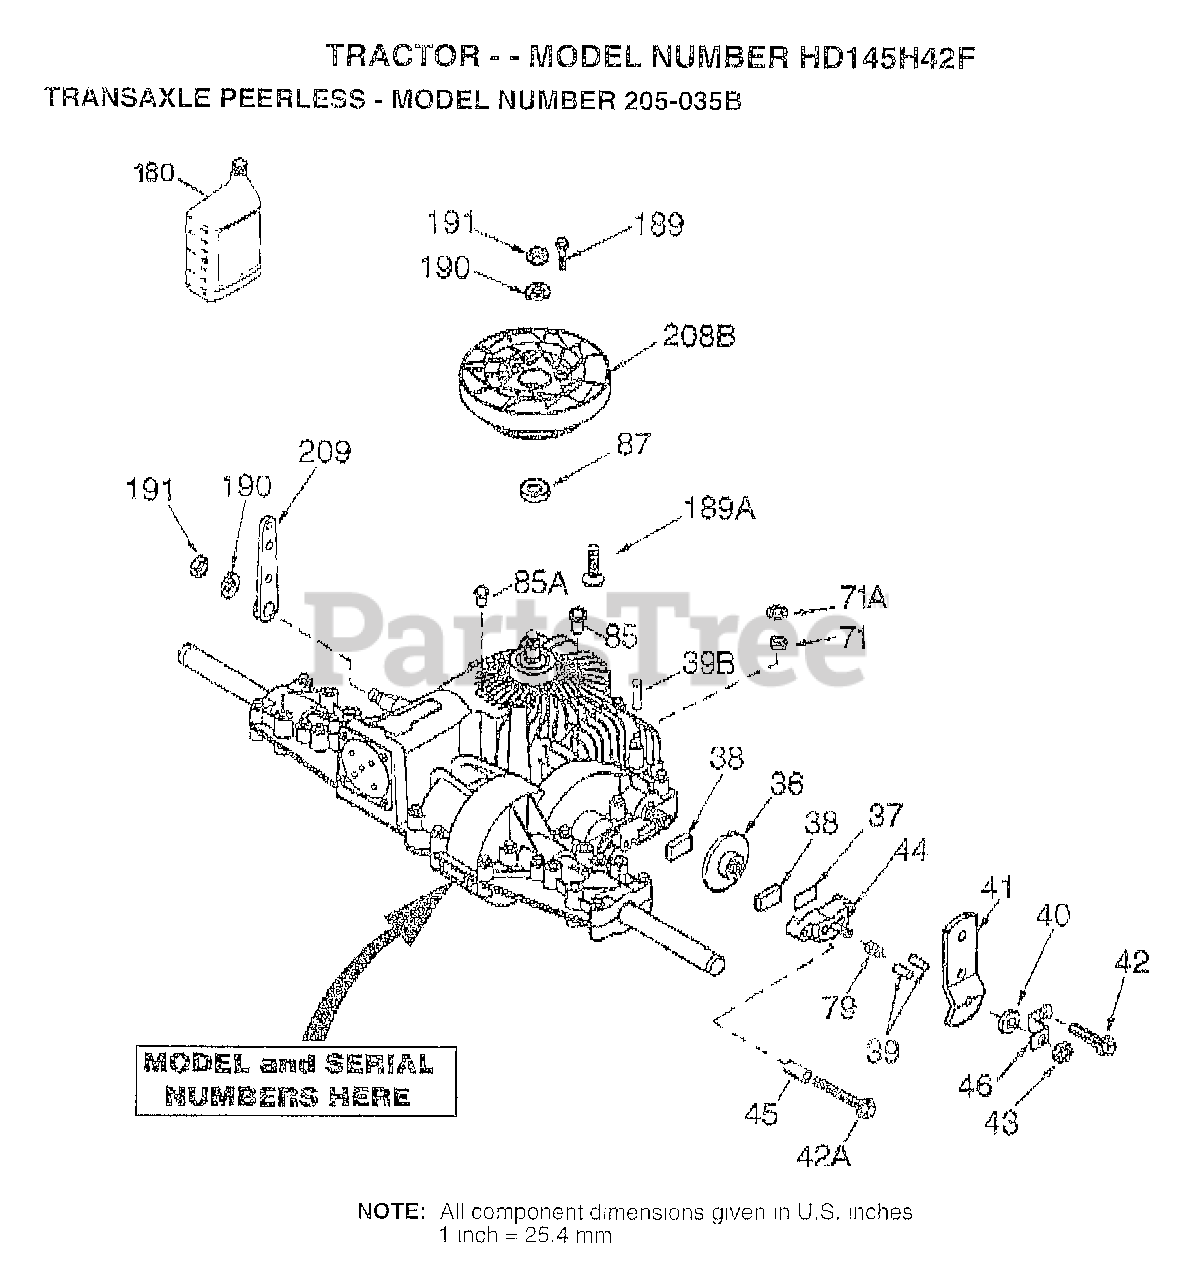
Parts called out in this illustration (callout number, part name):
37	PLATE BRAKE PAD
41	BRAKE LEVER
42	SCREW, 1/4-20 X 1-1/4
42A	SCREW, 1/4-20 X 2-1/4
43	LOCKNUT 5/16-24
44	HOLDER BRAKE PAD
46	BRAKE LEVER BRACKET
71	SEAL SQUARE CUT
85	OIL FILL PLUG
85A	TUBE PLUG, 3/8"
180	GEAR OIL 80W90
189	DRIVE SCREW
208B	FAN/COUPLING
209	CONTROL LEVER
